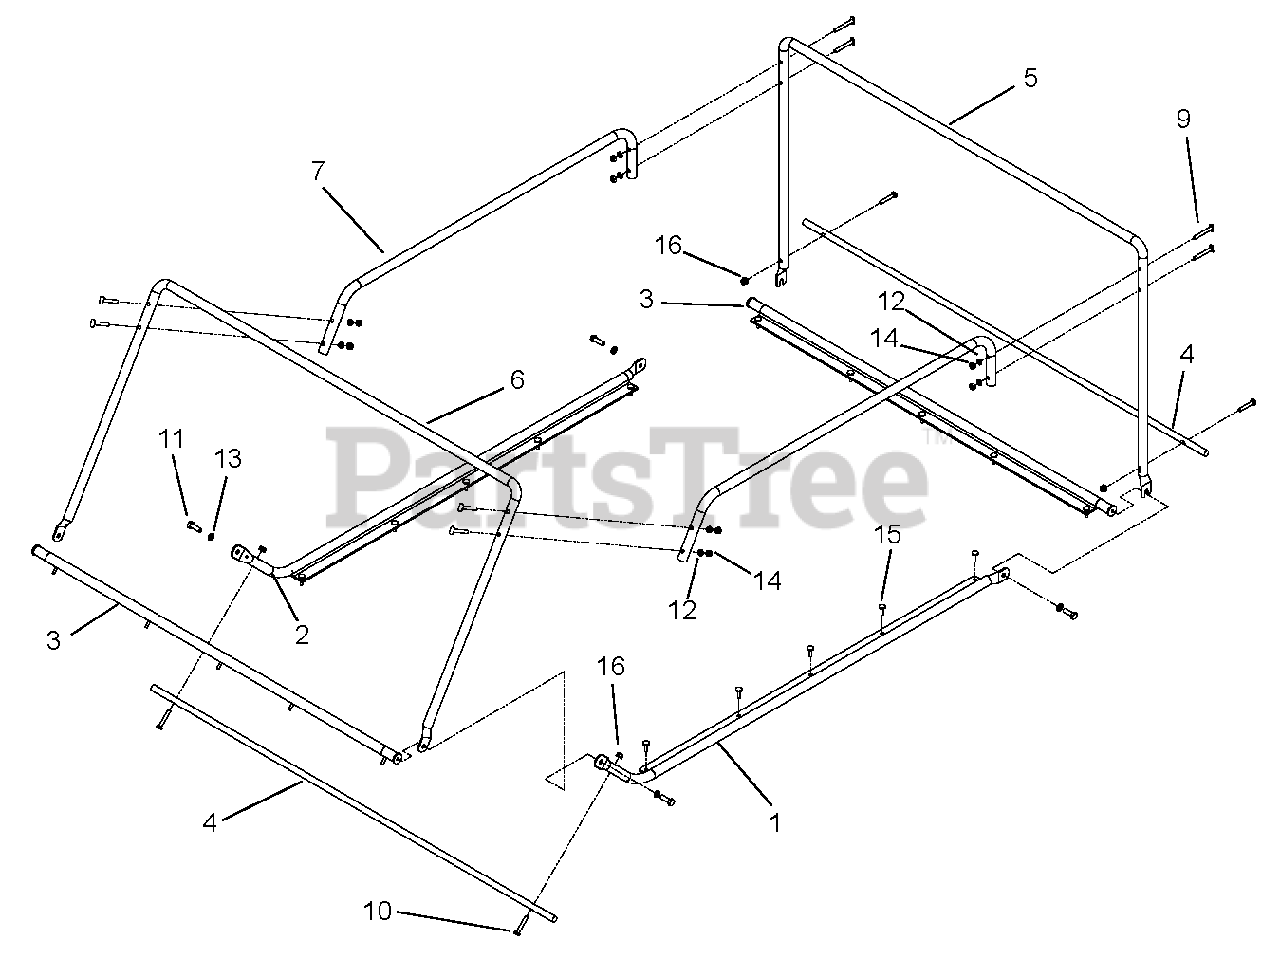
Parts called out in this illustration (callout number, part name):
10	4
11	4
12	8
13	4
14	8
16	4
